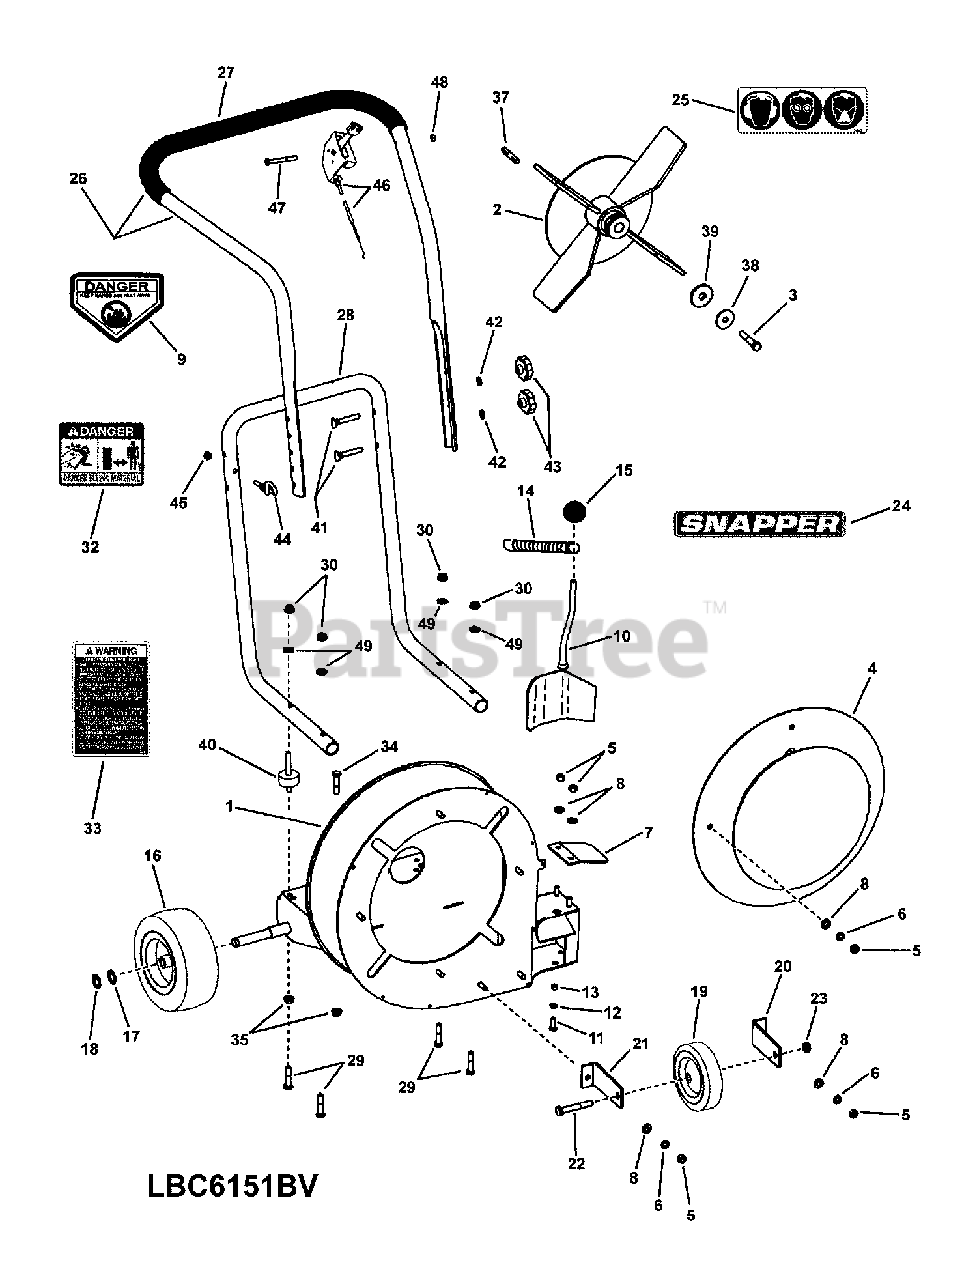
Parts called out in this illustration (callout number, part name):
1	WELDMENT, Base & Housing, 52 Classic
2	WELDMENT, Steel Impeller, 4 Blade, 15.00 O.D.
3	SCREW, 3/8-24 x 2" Hex Head Cap, GR 5
4	WELDMENT, Intake Baffle
5	NUT, 5/16-18 Hex, GR 5 or B
6	WASHER, 5/16" Split
7	DEFLECTOR, Side Air
8	WASHER, .34 x .69 x .08 Flat
9	DECAL, Danger, Cut Finger (CPSC)
10	WELDMENT, Door Front/Side Discharge
11	SCREW, 1/4-20 x 3/4" Hex Head Cap, GR 5
12	WASHER, .263 x .375 x .062 Split Lock
13	BUSHING, Steel Sleeve .250 I.D. x .375 O.D. x .25 long
14	SPRING, Extension
15	KNOB, #230 Dimco (3/8-16 thread)
16	*ASSEMBLY, Wheel & Tire, Sawtooth 4.10/3.50-4 Kenda
17	WASHER, .64 x .99 x .05 Flat
18	RING, External Retaining
19	WHEEL, 6.00 x 1.50 Semi-Pneumatic
20	BRACKET, Caster- RH
21	BRACKET, Caster- LH
22	SCREW, 3/8-16 x 2-1/2" Hex Head Cap, GR 5
23	NUT, 3/8-16 Hex Center Lock, GR 5 or B
24	DECAL, Blower
25	DECAL, Personal Protection
26	ASSEMBLY, Upper Handle & Grip- Narrow
27	GRIP, 1.0 x 21-1/2" Foam
28	HANDLE, Lower Folding, Narrow, Blower
29	SCREW, 5/16-18 x 1-3/4" Hex Heasd Cap, GR 5
30	NUT, 5/16-18 Hex Nyloc
32	DECAL, Danger, Flying Material
33	DECAL, Leaf Blower Warning
34	SCREW, 5/16-18 x 1-1/2" Hex Head Cap, GR 5
35	NUT, 5/16-18 Hex Flange Lock, GR 5
37	KEY, 1/4" Square x 2"
38	WASHER, .411/.406 I.D. Cone
39	WASHER, .468 x 1.625 x .25 Flat
40	MOUNT, Vibration (5/16-18 threads, both ends)
41	BOLT, 5/16-18 x 2" Curved Head Square Neck, GR 2
42	WASHER, 5/16" Internal Tooth Lock
43	KNOB, Folding Handle
44	ROPE GUIDE (1/4-20 thread)
45	NUT, 1/4-20 Hex Center Lock, GR 5 or B
46	THROTTLE CONTROL, B&S, 35.00/1.62
47	SCREW, 1/4-20 x 2" Hex Head Cap, GR 5
48	NUT, 1/4-20 Hex Nyloc
49	WASHER, 5/16" Curved
